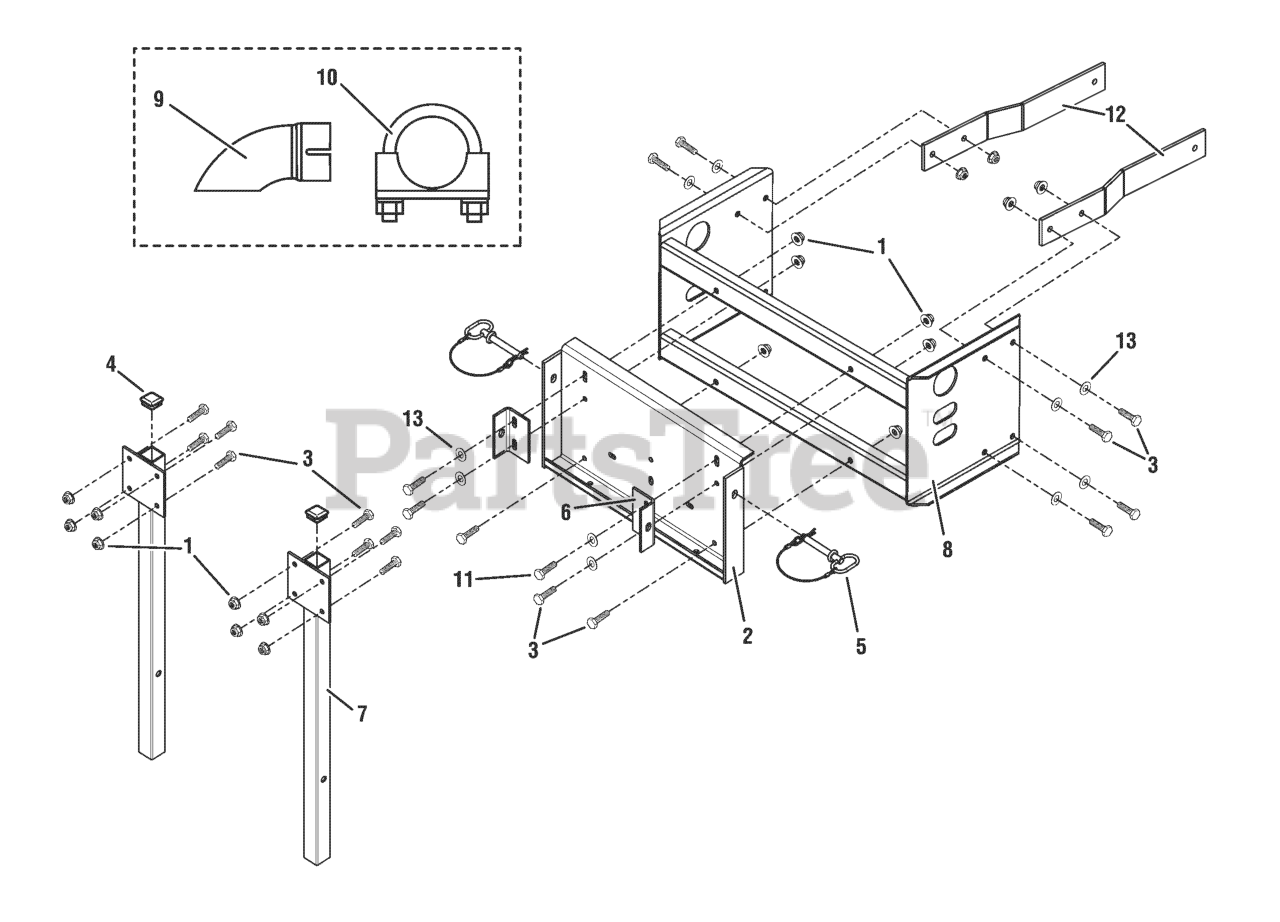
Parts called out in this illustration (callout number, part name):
1	NUT, 3/8-16 HEX NYLOCK FLANGE
2	WELD, 3-BAG MOUNT, ALL - BLK
3	BOLT, 3/8-16 X 1" GD5 CZ
4	CAP, PLASTIC, 1-1/2 X 1-1/2
5	PIN, HITCH, .50 X 3.25 W/ LAY
6	MOUNT, TAB, BLACK
7	WELD, MOUNT, POST NZM - BLK
8	WELD, BAGGER MOUNT NZM
9	ELBOW, EXHAUST, KOH. 24-265-07-S
10	CLAMP, MUFFLER, 47-237-04-S
11	BOLT, 3/8-16 X 1-1/4" GD5 CZ
12	BRACKET, REAR GUARD MOUNT - BLK
13	3/8 STD WASHER
